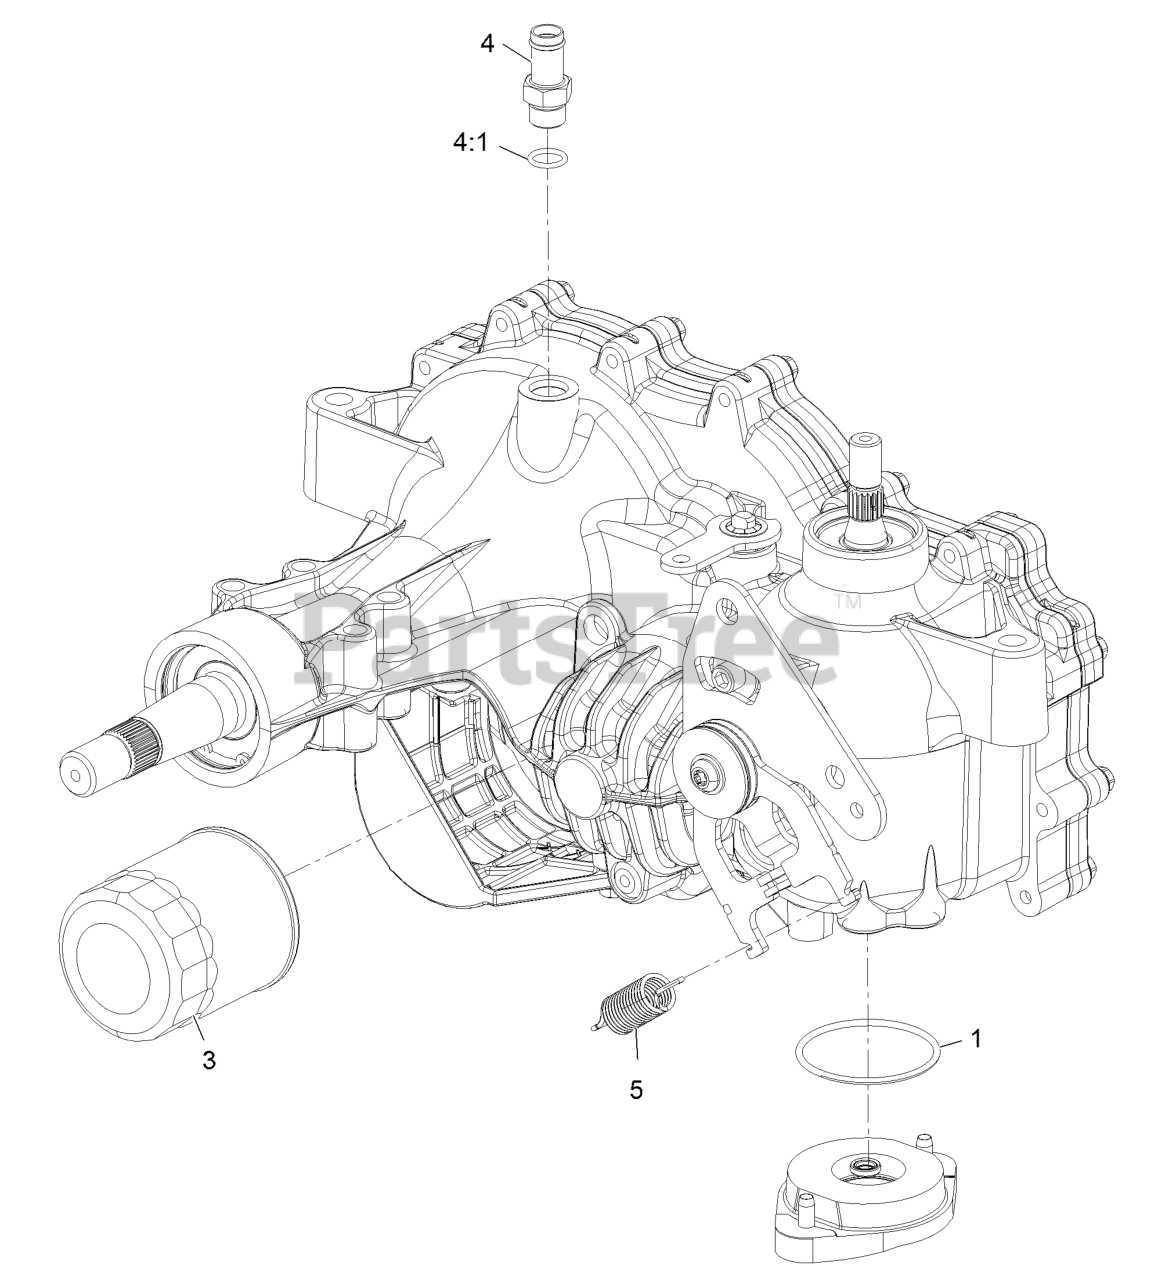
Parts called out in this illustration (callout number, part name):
1	O RING-SEAL
3	ELEMENT-OIL FILTER, HYD
4	ADAPTER-STRAIGHT
5	SPRING-EXTENSION
